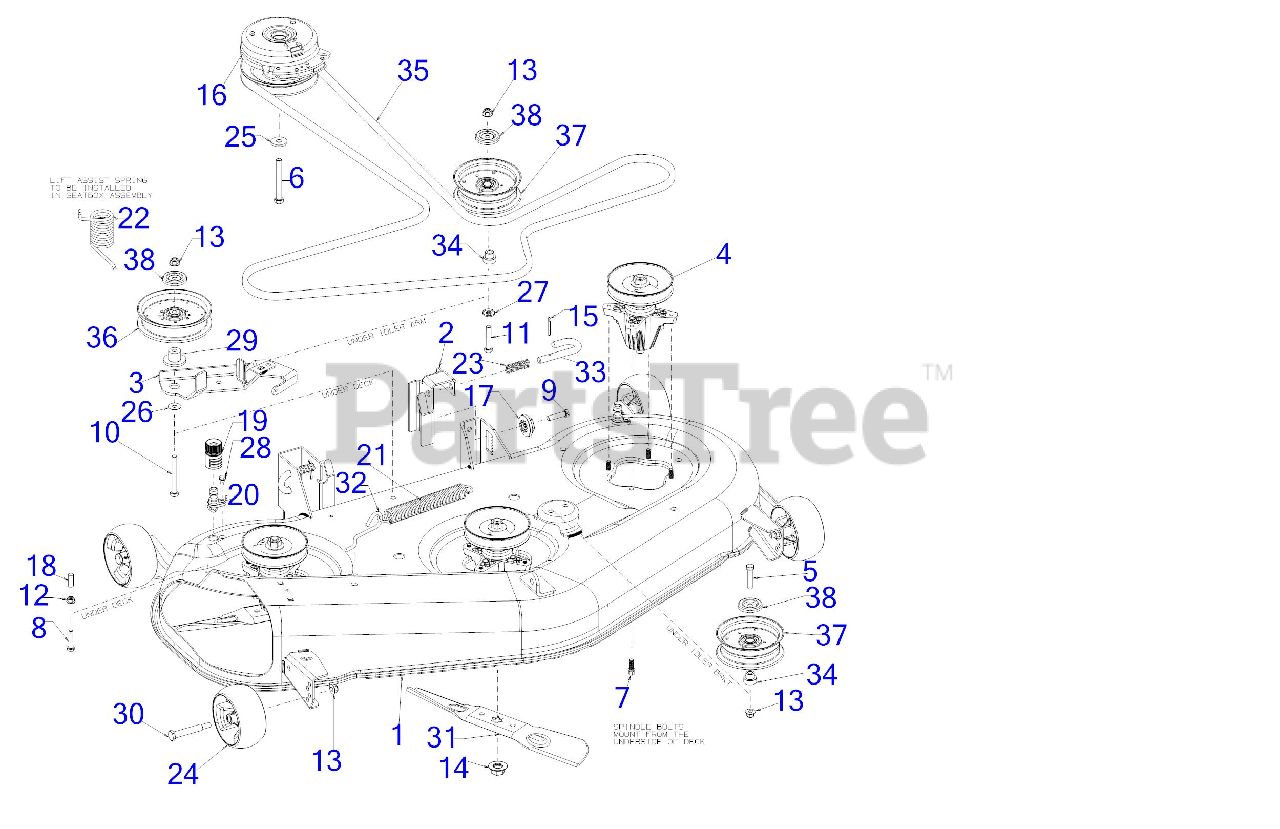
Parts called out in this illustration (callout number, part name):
4	SPINDLE ASSEMBLY
4	Cub Cadet 50" SPINDLE ASSEMBLY (06980)
5	HEX SCREW 3/8-16 x 1.75 GR5
6	SCREW 7/16-20 x 3.5 GR5
7	SCREW 5/16-18 X .875
8	SCREW 5/16-18 x 1.5 LG
9	SCREW 3/8-16X1.5 GR5
10	SCREW 3/8-16 x 3.25 GR8
11	SCREW 3/8-16 x 2.0 GR5
12	FLANGE LOCK NUT 5/16-18
15	COTTER PIN-5/32 DIA
16	ELECTRIC PTO CLUTCH
17	DECK ADJUSTMENT GEAR
19	WATER NOZZLE
20	DECK WASH NOZZLE
21	EXTENSION SPRING
22	TORSION SPRING
23	COMPRESSION SPRING
24	DECK WHEEL
24	WHEELS-DELUXE 5"
25	FLAT WASHER .445 x 1.248 x .170
26	FLAT WASHER
28	SHOULDER SCREW 1/4-20 x .50
29	SHOULDER SPACER
30	SHOULDER BOLT
31	17.27" BLADE (2N1)
31	Cub Cadet 50" HI LIFT BLADE SET
31	Genuine Factory Parts 50" BLADE SET
31	50" 6 PT STAR LOW LIFT/SAND BLADE
31	Cub Cadet 50" LOWLIFT BLADE SET
31	Genuine Factory Parts 50" LOWLIFT BLADE SET
31	50" 6 PT STAR XTREME MULCH BLADE
31	Cub Cadet 50" XTREME BLADE SET
31	Genuine Factory Parts 50" XTREME MULCH BLADE SET
32	DECK SPRING HOOK
33	DECK RELEASE PIN
34	SHOULDER SPACER
35	V-BELT B SEC x 143.5 LG
35	Cub Cadet 50" DECK DRIVE BELT
35	Troy-Bilt 50" DECK DRIVE BELT
36	FLAT IDLER PULLEY
37	IDLER PULLEY 4.50" DIA
38	IDLER PULLEY CAP
